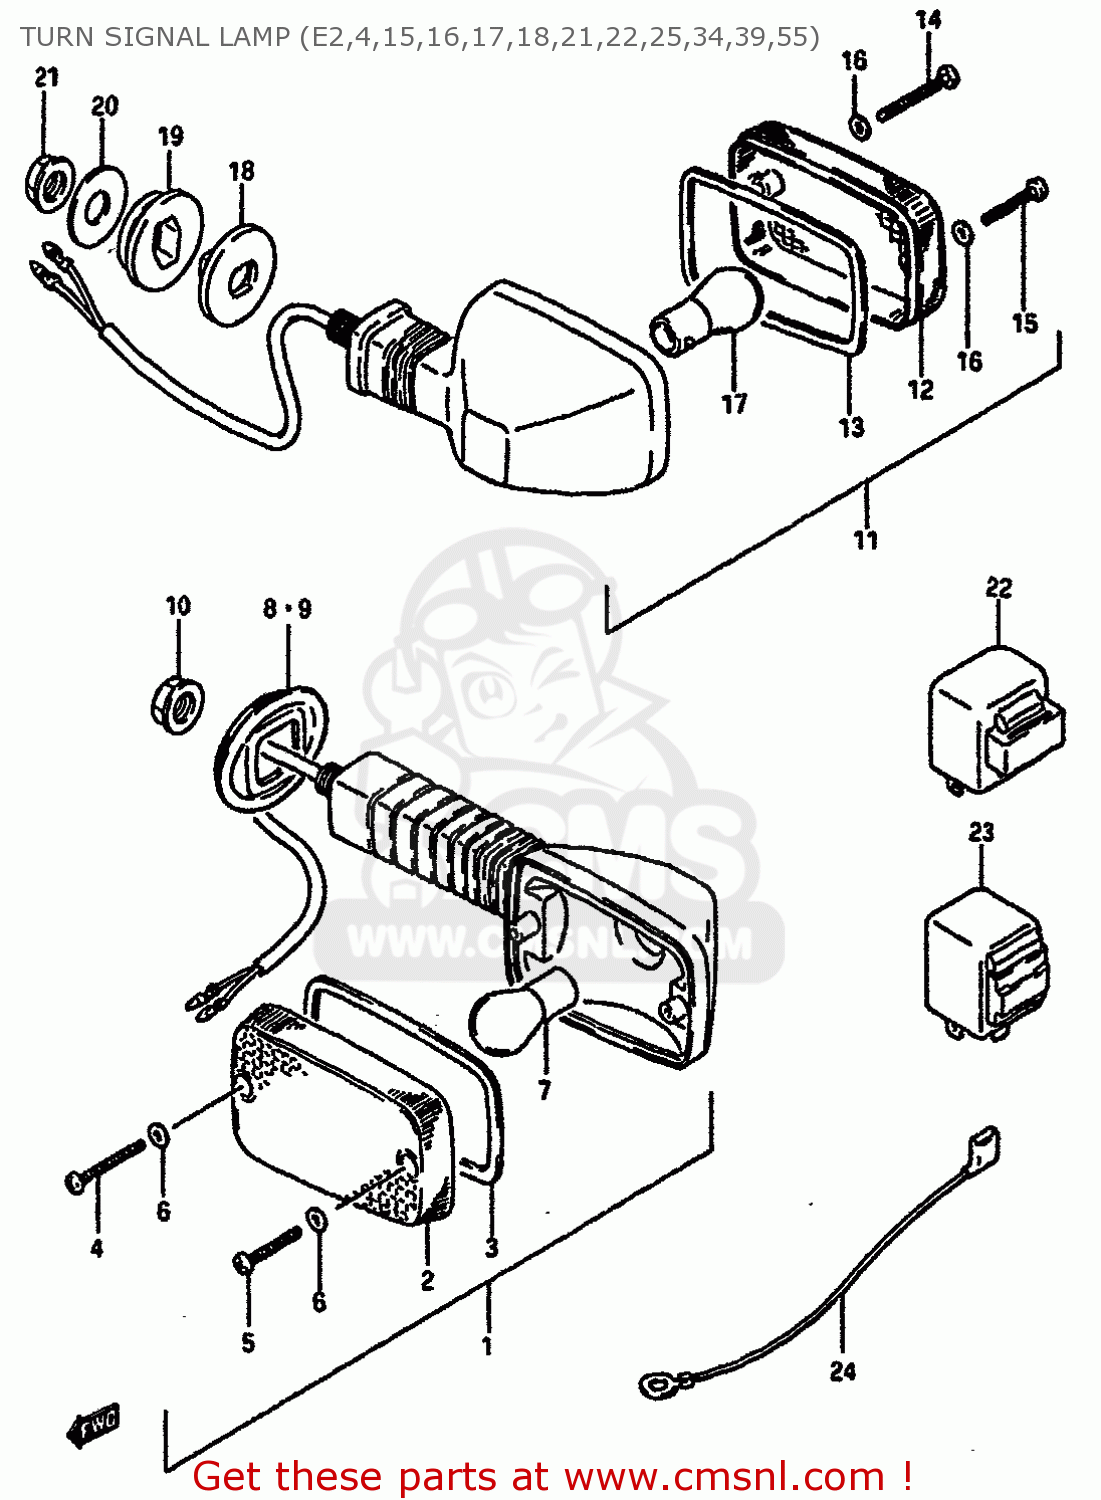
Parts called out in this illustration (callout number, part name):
1	LAMP ASSY,FRONT TURN SIGNAL
2	LENS,FR
3	GASKET (NAS)
4	SCREW,TURN SIG LENS FITTING
5	SCREW
6	GASKET (NAS)
7	BULB(12V21W)
8	GROMMET, FRONT RH
9	GROMMET, FRONT LH
10	NUT
11	LAMP ASSY,REAR TURN SIGNAL
12	LENS,RR
13	GASKET (NAS)
14	SCREW,TURN SIG LENS FITTING
15	SCREW
16	GASKET (NAS)
17	BULB(12V21W)
18	SPACER
19	CUSHION
20	WASHER (10.2X27X1.6)
21	NUT
22	RELAY ASSEMBLY,TURN SIGNAL
23	RELAY ASSY,TUR
24	LEAD WIRE
